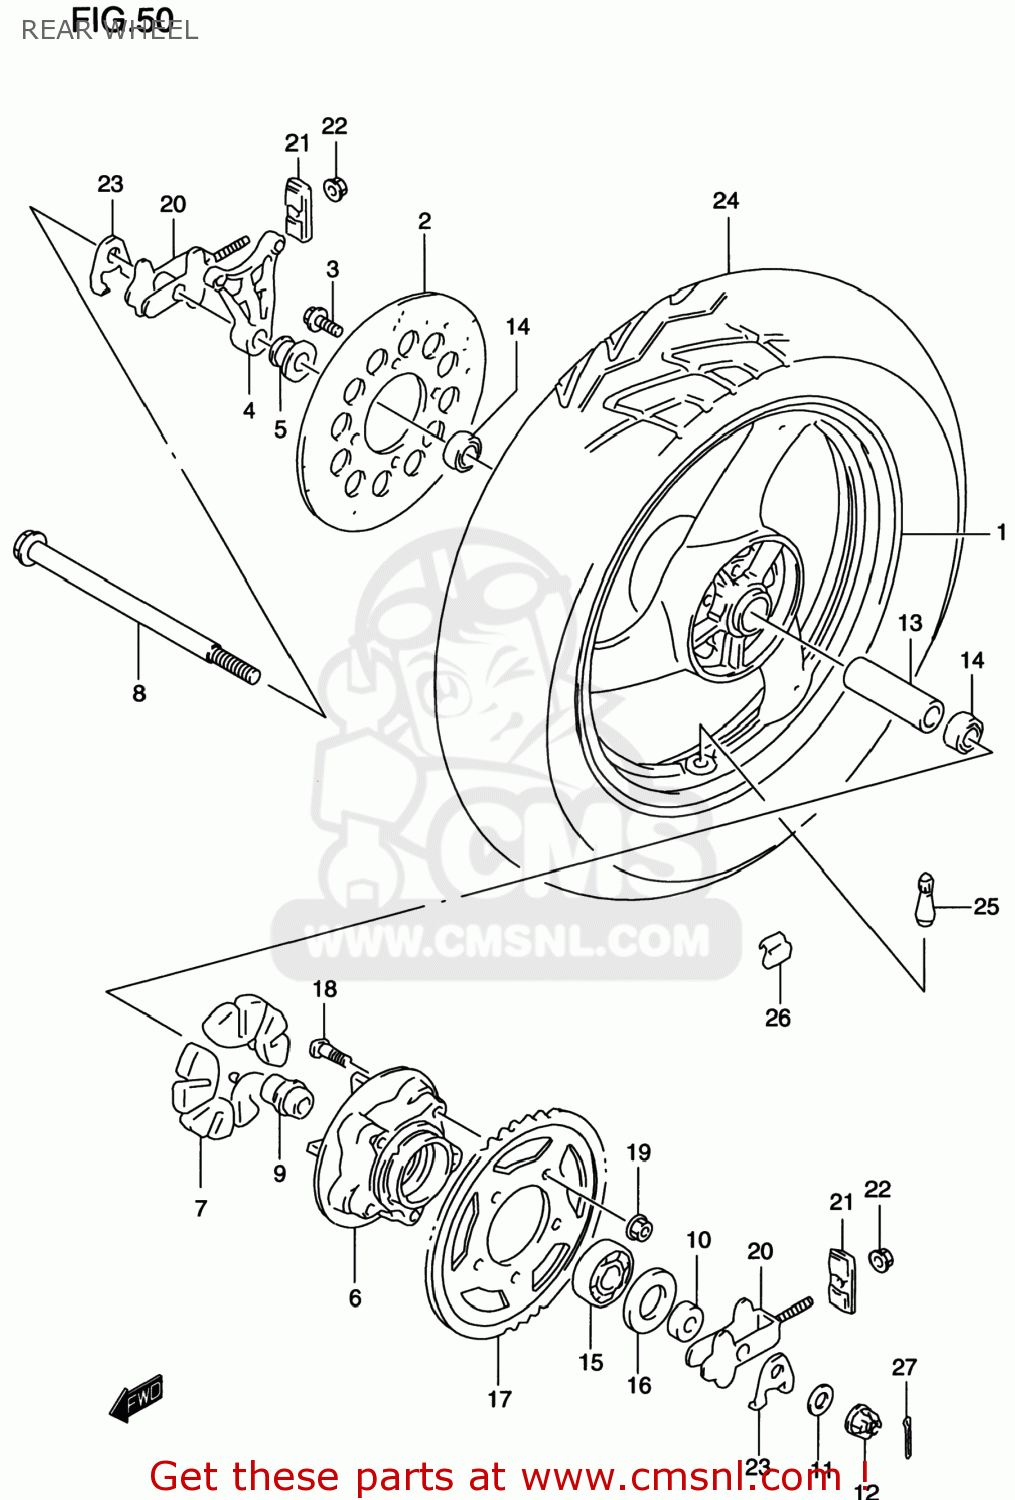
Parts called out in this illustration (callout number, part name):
1	WHEEL,REAR (MT3.50X17)
2	DISC,RR BRAKE
3	BOLT(8X30)
4	BRACKET,RR,CALIPER
5	SPACER,RR AXLE,R
6	DRUM,RR SPROCKET
7	ABSORBER,RR HUB SHOCK
8	AXLE,REAR
9	RETAINER,RR SPROCKET DRUM
10	SPACER,RR AXLE,L
11	WASHER(17X30X3)
12	NUT
13	SPACER(17.5X25X88)
14	BEARING
15	BEARING(25X62X17)
16	SEAL,OIL(35X62X8)
17	SPROCKET,RR(NT:39-520)
18	BOLT
19	NUT
20	ADJUSTER,CHAIN
21	PLATE,CHAIN ADJUSTER GUIDE
22	NUT
23	WASHER,CHAIN ADJUSTER
24	TIRE,T/L(130/70-17 62H)
25	VALVE ASSY,WHEEL RIM(TR412)
26	BALANCER,WHEEL (10G)
27	PIN,COTTER
